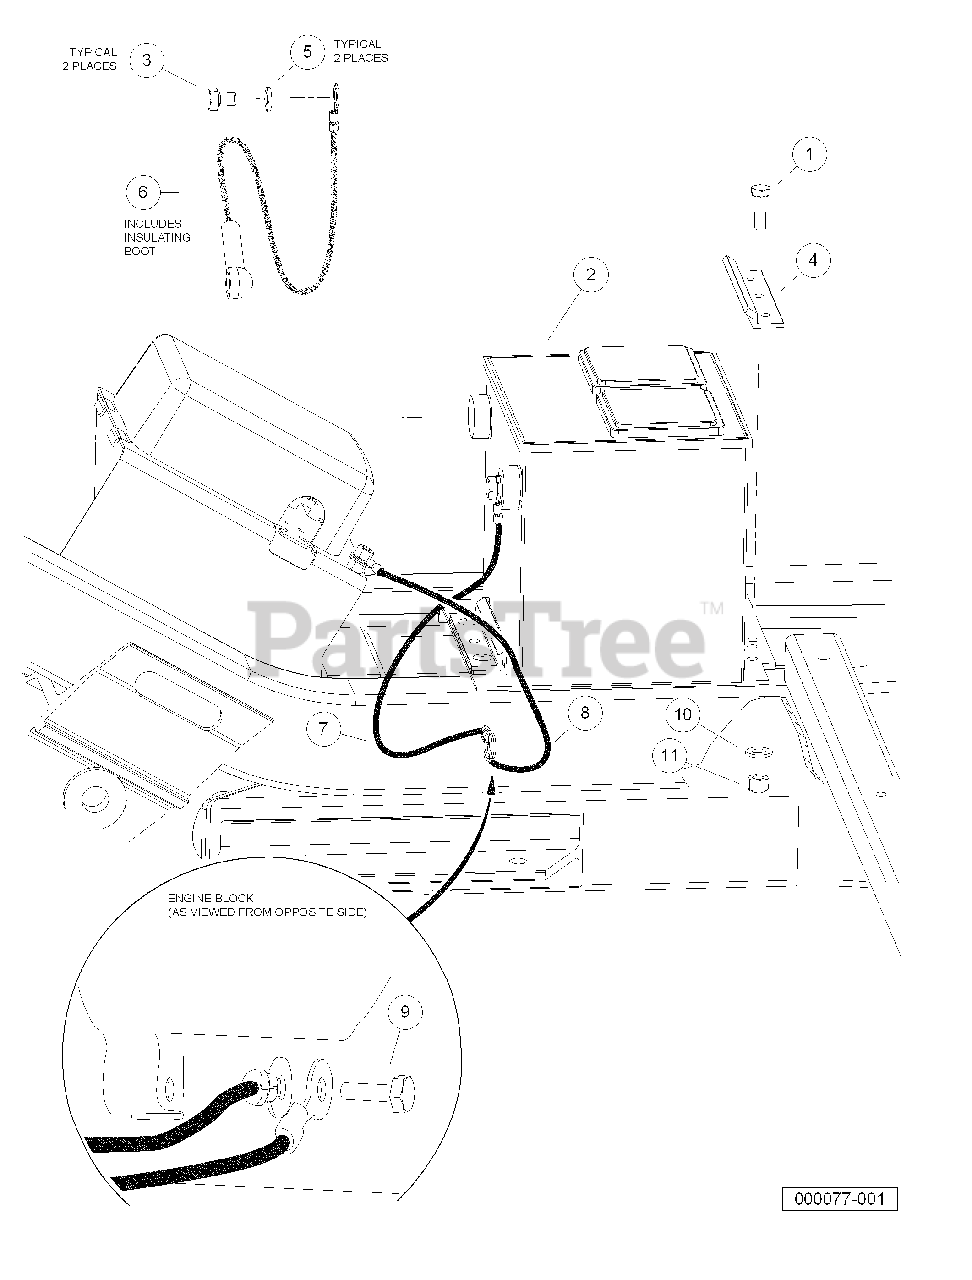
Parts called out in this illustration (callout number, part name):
1	Screw, 5/16-18 X 1.00 Hex Cap
2	Battery, 12-Volt
3	Screw, 3/8-16 X 0.50 Stainless Steel Hex-Head
4	Clamp, Battery
5	Lockwasher, 3/8 Stainless Stl
6	Asm, #6 Red Wire
7	Asm, #6 Blk Wire
8	Asm, #6 Blk Wire
9	Bolt, M6 X 1 X 16 Loctite
10	Washer, 5/16 Type A Flat
11	Locknut, 5/16-18 Nylon Insert
